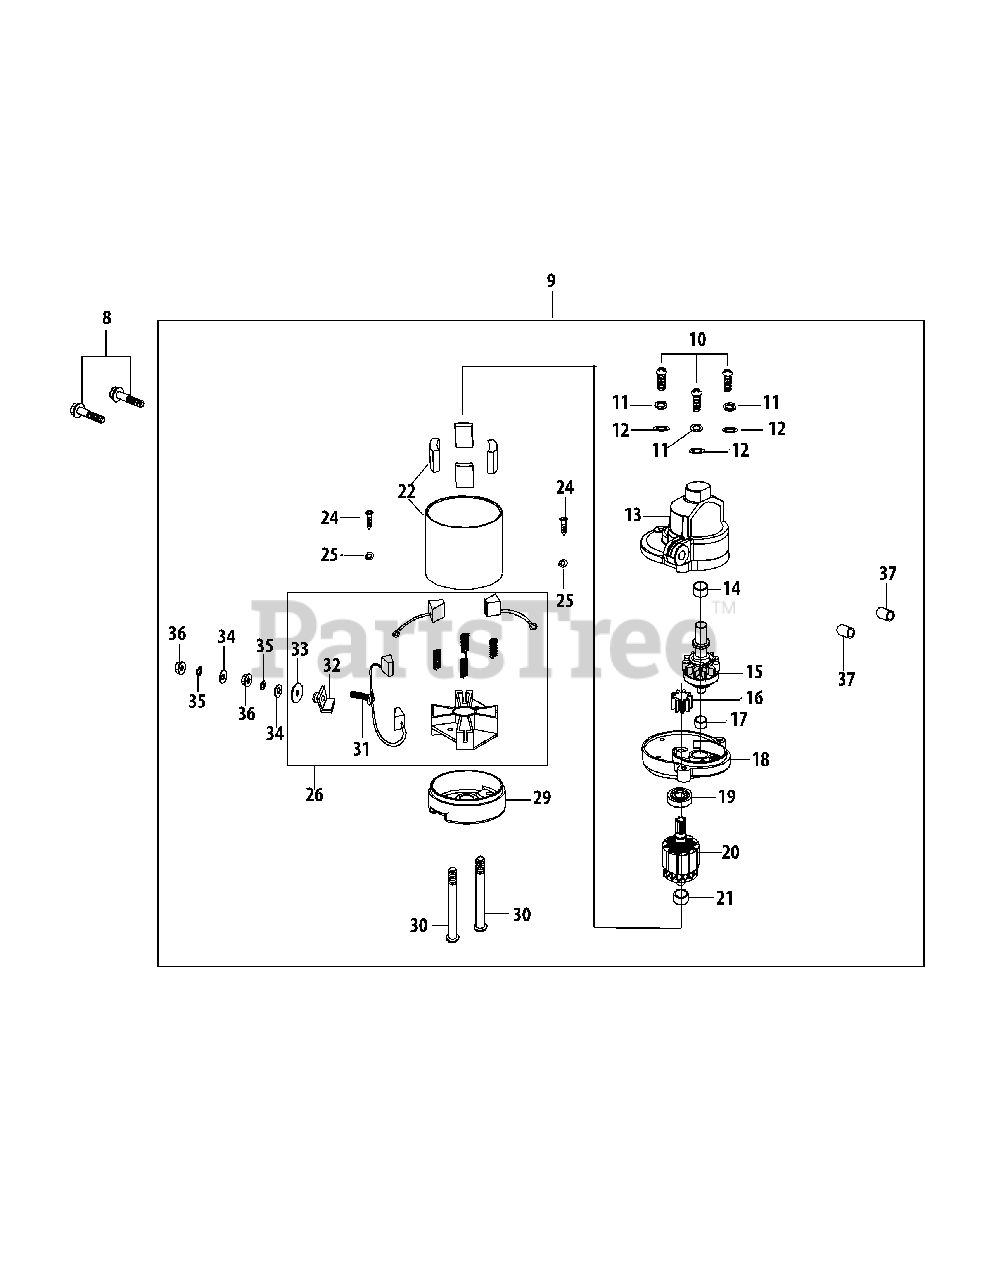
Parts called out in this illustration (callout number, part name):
8	Bolt M8×40
9	Starter Assembly
10	Screw M5×25
11	Lock Washer 5
12	Plain Washer 6
13	Electrical Starter Front Cover
15	Pinion/Clutch Assembly
18	Pinion Cover
19	Bearing 6001Zz
20	Starter Armature
22	Starter Housing Assembly
25	Lock Washer
26	Brush Assembly
29	Electrical Starter Back Cover
30	Bolt M6×100
31	Bolt M6×30 Assembly
32	Waterproof Washer
33	Insulation Washer
34	Plain Washer 6
35	Lock Washer 6
36	Nut M6
37	Dowel Pin 10×14
